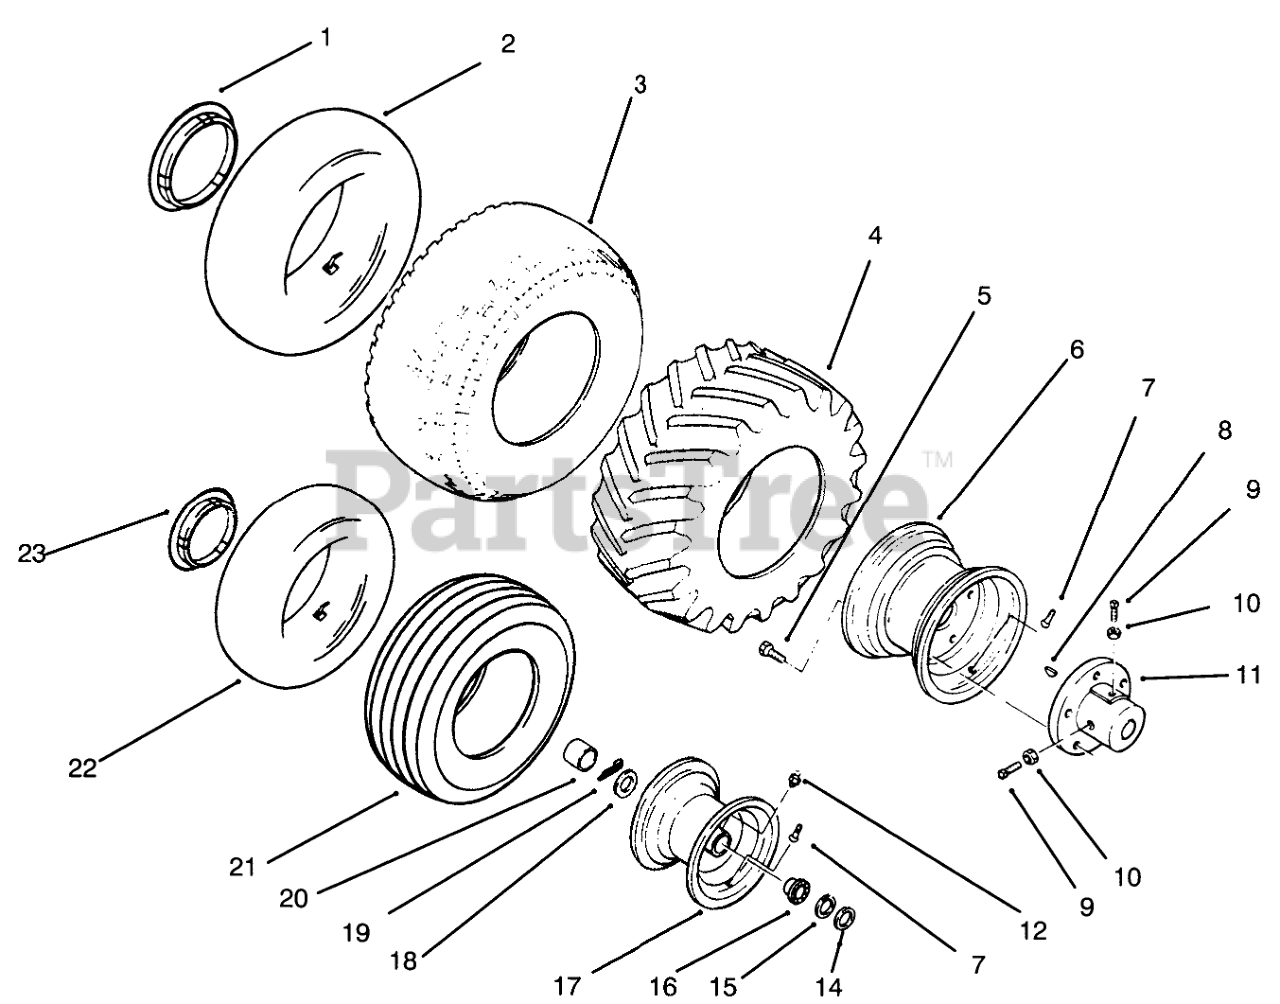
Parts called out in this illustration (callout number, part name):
1	12"-HUB CAP LOGO
2	Tube-Rear (Opt.)
3	TIRE
4	Tire-Cleat, Rear
5	BOLT-LUG
6	WHEEL
7	VALVE
8	KEY-WOODRUFF
9	SCREW-SET, SQH
10	NUT-JAM
11	Hub Rear
12	ZERK-GREASE
14	WASHER-SHIM
15	WASHER
16	BEARING-WHEEL
17	Wheel
18	Washer-Special Hub Cap
19	PIN-COTTER
20	HUB CAP-FLAT BLACK
21	Tire (16 x 6.5-8) 2-Ply -2 Wheel Axel
23	6"-HUB CAP LOGO
